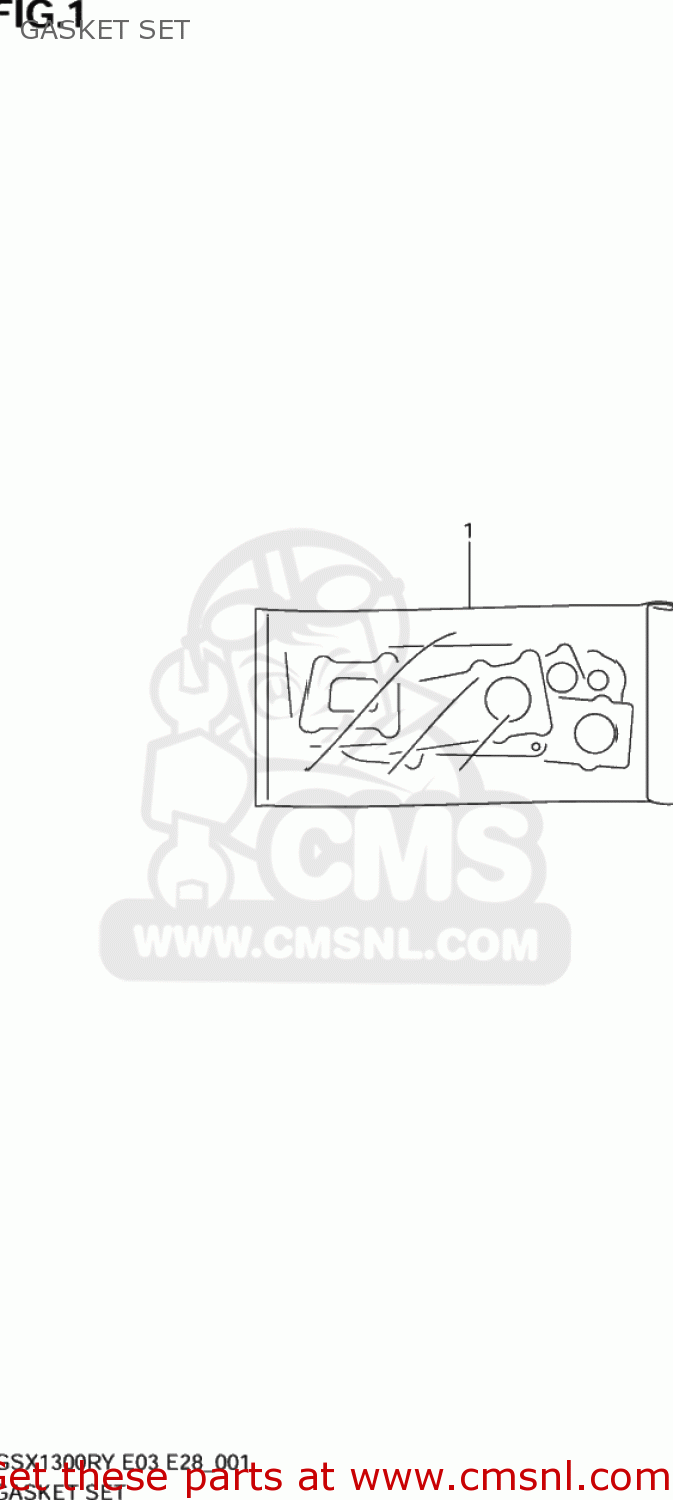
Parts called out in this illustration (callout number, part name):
1	GASKET SET (NAS)
2	GASKET,CYLINDER HEAD (NAS)
3	GASKET,CYL HEAD COVER NO.1 (NAS)
4	GASKET,CYL HEAD COVER NO.2
5	GASKET,CYLINDER (NAS)
6	GASKET,BREATHER COVER (NAS)
7	GASKET,CL COVER (NAS)
8	GASKET,MAGNETO COVER (NAS)
9	GASKET,GEAR SHIFT COVER (NAS)
10	GASKET,OIL PAN (NAS)
11	GASKET,STARTER CLUTCH COVER (NAS)
12	GASKET,START IDLE GEAR CAP (NAS)
13	GASKET,TENSIONER ADJUSTER (NAS)
14	GASKET,EXHAUST PIPE (NAS)
15	GASKET,MUFFLER JOINT
16	O RING,OIL PUMP
17	WASHER(10.6X25.5X2.3)
18	O RING(D:2.4,ID:11.8)
19	O RING(D:2.62,ID:20.3)
20	O RING(D:3.1,ID:32.7)
